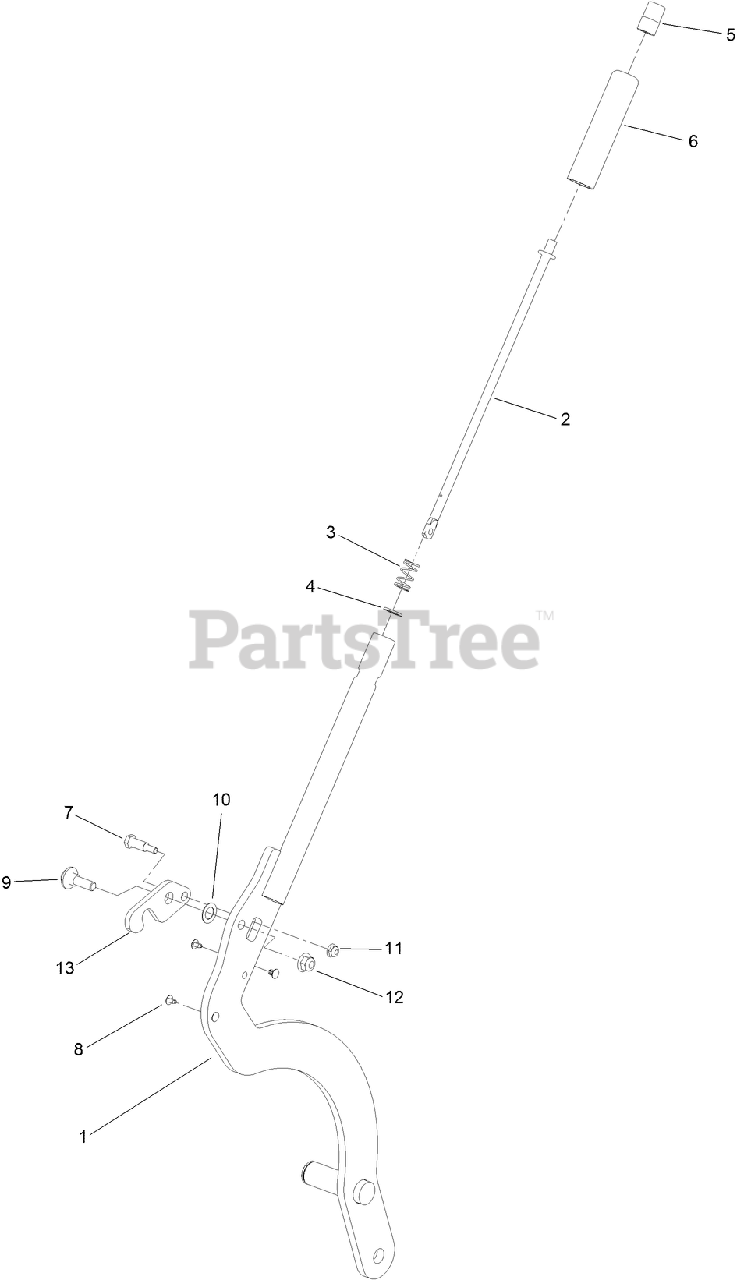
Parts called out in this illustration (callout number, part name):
1	LEVER-LIFT
2	ROD-LATCH, RELEASE
3	SPRING-COMPRESSION
4	WASHER-SPECIAL
7	BOLT-SHOULDER
9	SCREW-SHOULDER, HWH
10	WASHER
11	NUT-HF
12	NUT-HF, NI
13	LATCH-HOC
